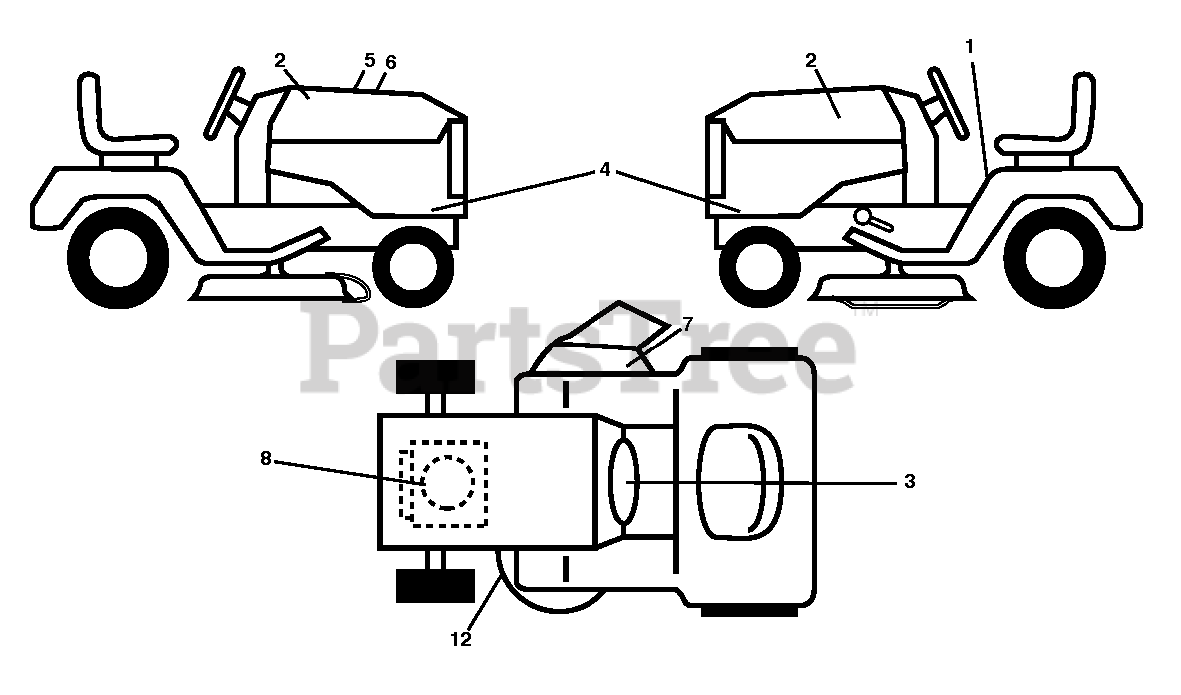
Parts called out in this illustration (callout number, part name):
1	DECAL.FENDER.WARNING.ENGLISH
2	DECAL.BADGE.170MM.TEXTLOGO.
3	DECALS.WARN.CA.SPKARREST/PROP
4	DECAL TRACTOR SIDE PANEL DECAL
5	DECAL.WARNING.CUST.RESP.E85.
6	DECAL RPL.K46.46C.B+S M33
7	DECAL, DECK DEFLECTOR, WARNING
8	DECAL.ENG.BS.18.5INTK.381713
12	DECAL.V-BELT.SCH.42/46"MEC/ELE
